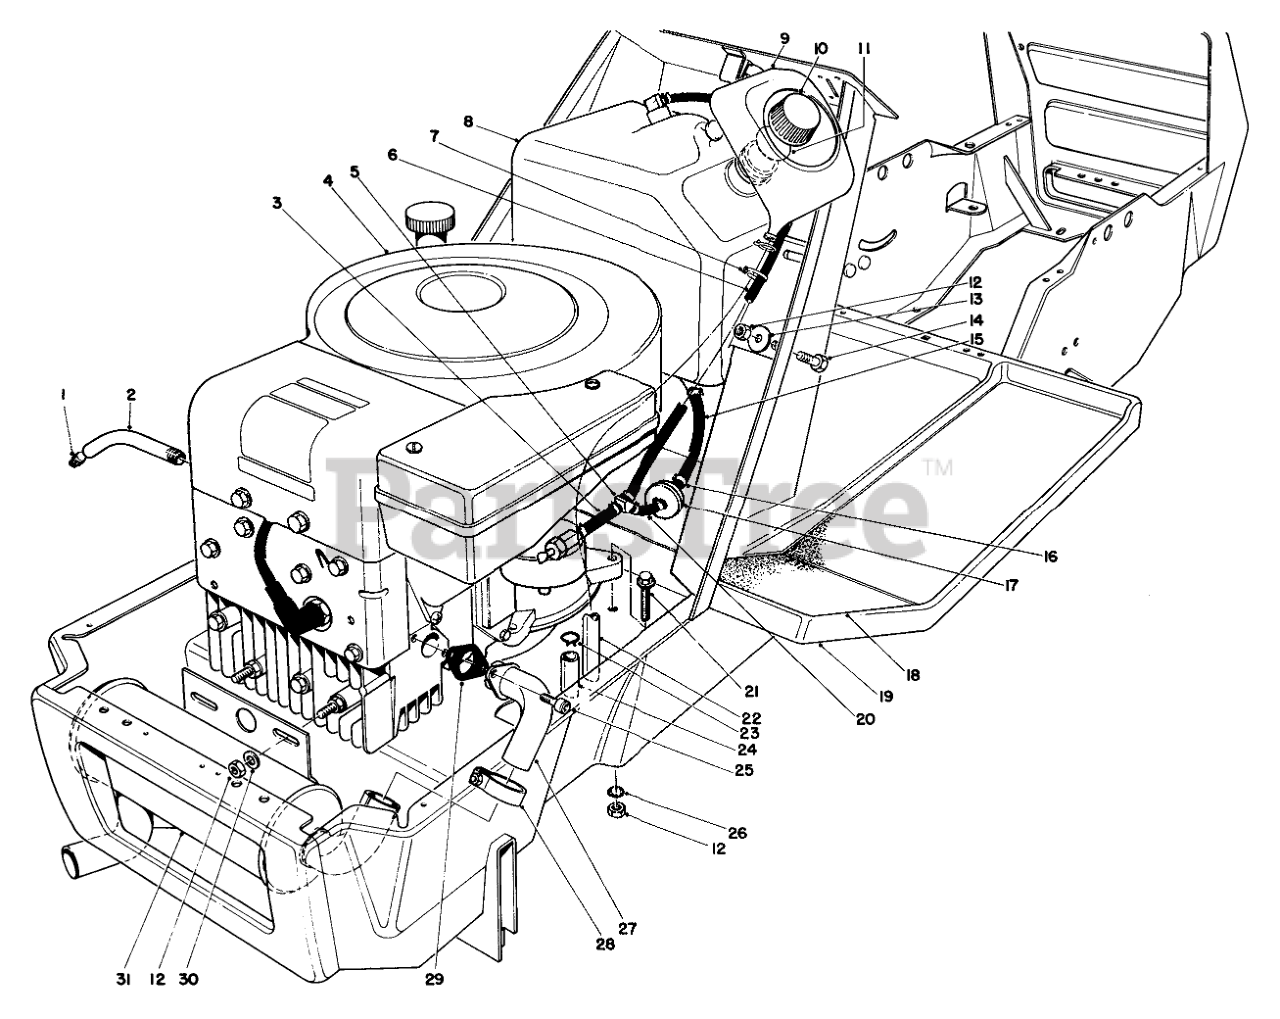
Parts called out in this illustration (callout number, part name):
1	PLUG-PIPE, SQH
2	OIL DRAIN TUBE
3	GAS HOSE
4	Engine
5	Fitting-Barbed Y
6	Hose-Gas Return
7	TIE-CABLE
8	Gas Tank Assy. (Incl. Ref. #9)
9	Funnel-Overflow
10	Gas Cap Assy. (Incl. Ref. #11)
11	Gasket Gas Cap
12	NUT-LOCK, CONE
13	WASHER
14	SCREW-HH
15	HOSE-FUEL
16	FUEL HOSE CLAMP
17	Nut
18	LH FOOT TREAD
19	Frame
20	GAS HOSE
21	SCREW-HH
22	Hose Funnel
23	HOSE CLAMP
24	Hose-Carburetor Drain
25	SCREW-HSH
26	WASHER-LOCK, INTERNAL
27	10 HP EXHAUST PIPE WA
28	MUFFLER CLAMP
29	Exhaust Gasket
30	WASHER-PLAIN
31	EXHAUST MUFFLER 10 HP
